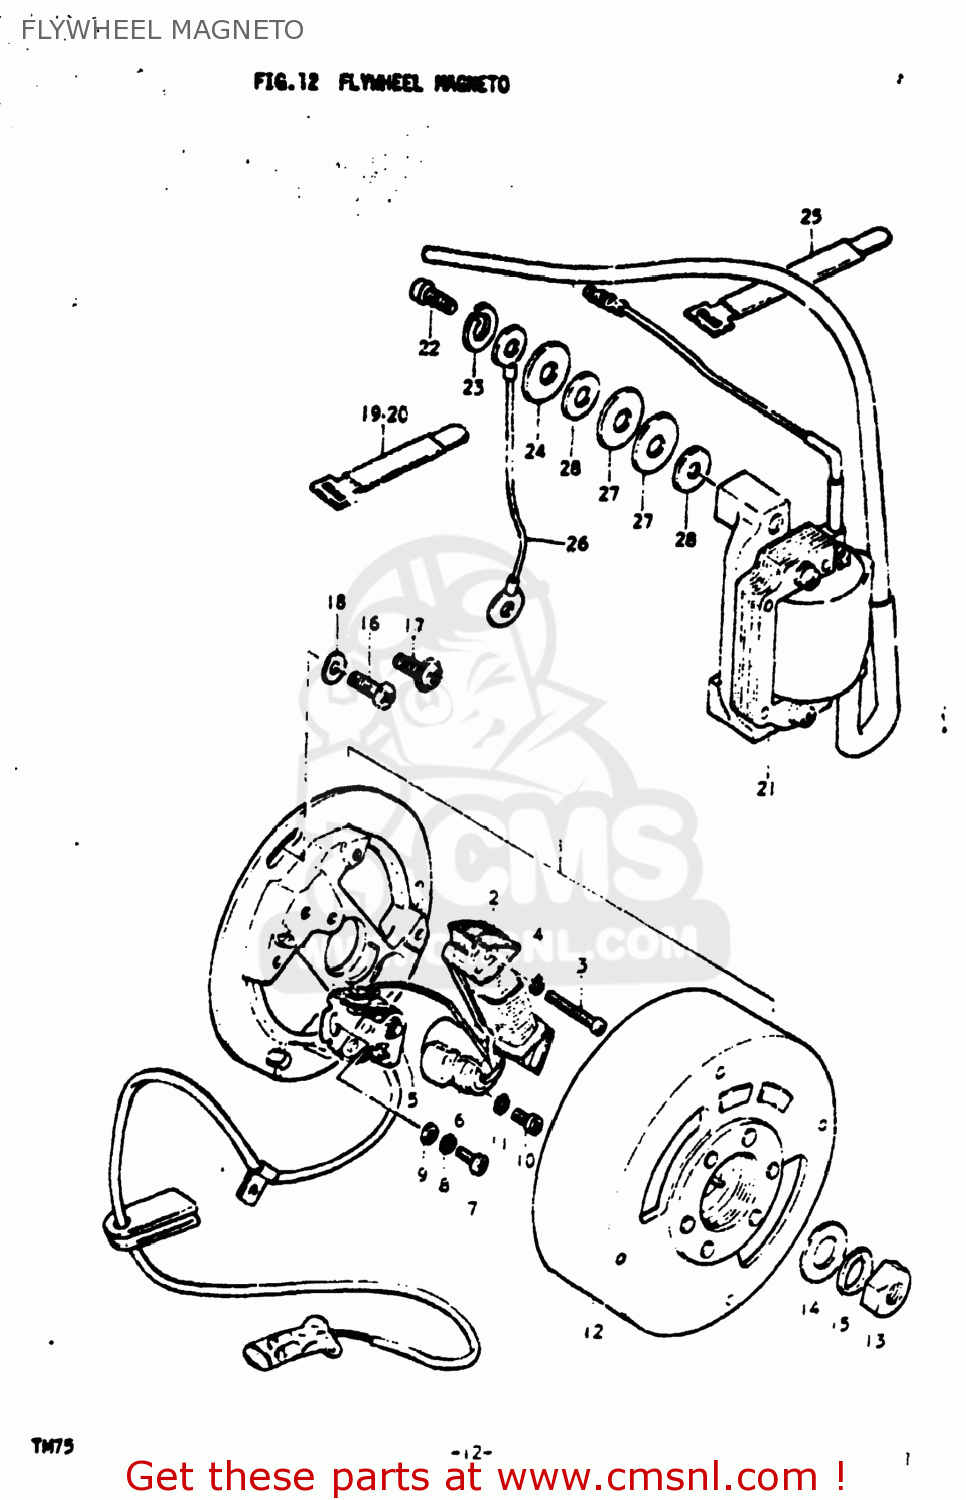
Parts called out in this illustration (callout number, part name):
1	MAGNETO ASSEMBLY
2	COIL
3	SCREW
4	LOCK WASHER
5	POINT ASSEMBLY,CONTACT
6	CONDENSER
7	.SCREW
8	LOCK WASHER
9	WASHER
10	SCREW
11	LOCK WASHER
12	ROTOR ASSEMBLY
13	NUT
14	WASHER
15	LOCK WASHER
16	SCREW
17	SCREW(5X14)
18	WASHER
19	CLAMP(L:250)
20	CLAMP
21	COIL ASSEMBLY,IGNITION
22	Screw
23	LOCK WASHER
24	WASHER
25	CLAMP(L:250)
26	WIRE
27	WASHER
28	WASHER
